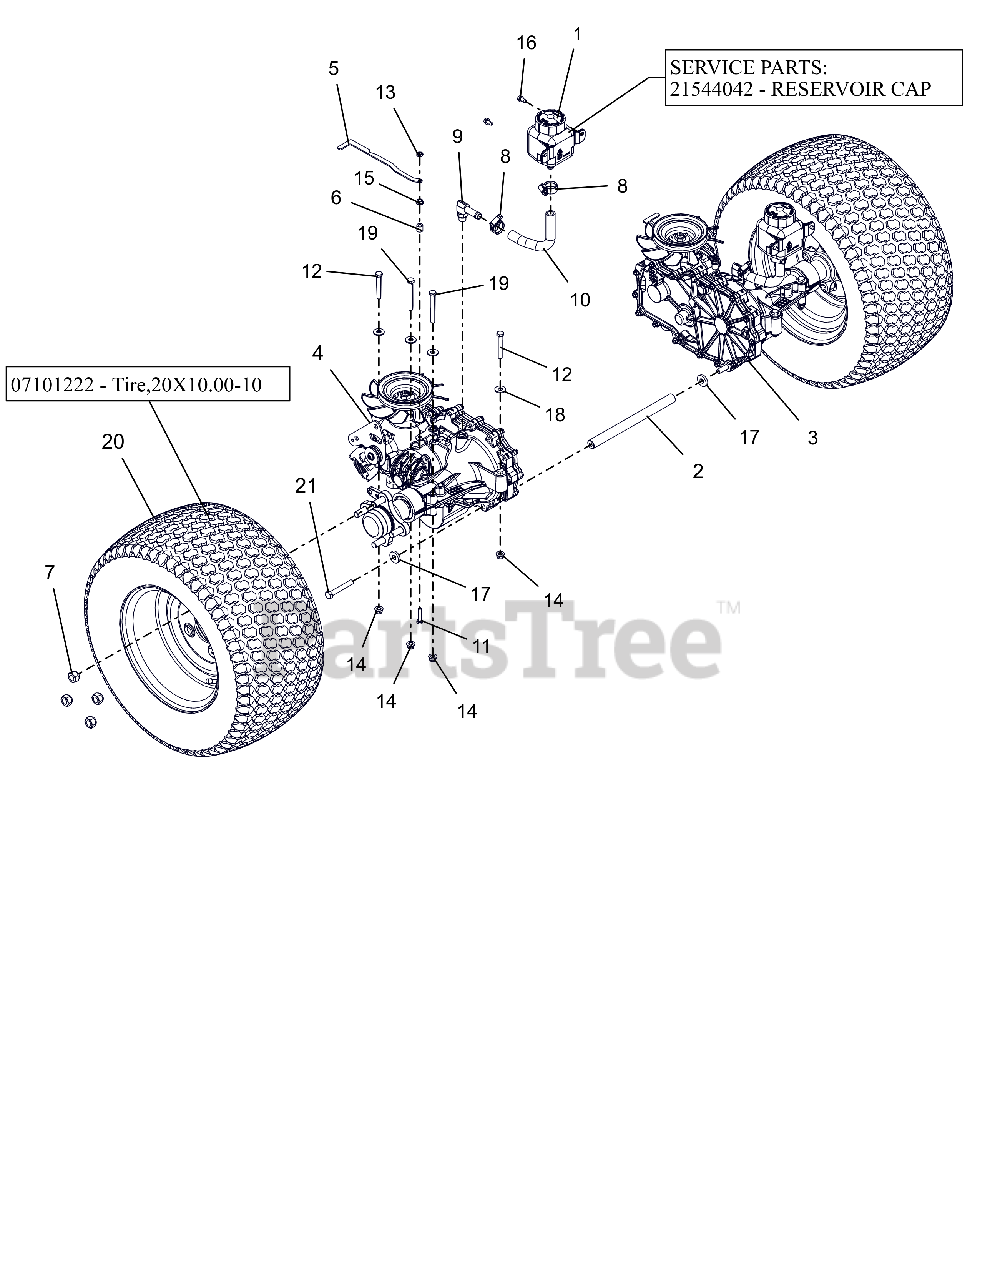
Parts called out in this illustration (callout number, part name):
1	TANK, EXPANSION
1	CAP, HYDRO RESERVOIR REPLAC.
2	ROD, TRANSAXLE BRACE (LONG)
3	TRANSAXLE,ZT2800 LH
4	TRANSAXLE,ZT2800 RH
5	BRKT, DUMP VALVE
6	BSHG-SLV .265X.500X.500
7	WHEEL NUT .500-20 YZ
8	CLAMP,.88 DIA. HOSE
9	FITTING, HYD (90 DEG)
10	HOSE, FORMED LH XL
11	@BLT-HEX .25-20X1.25 GR5 YWZC
12	@BLT-HEX .31-18X2.25 GR5 YWZC
13	NUT-LK-CTR JAM .25-20 YWZC
14	@NUT-LK-NYL-FLG .31-18 YWZC
15	@NUT-SPNLK-FLG .25-20 YWZC
16	SCR-TAP .25-20X.50 HWH TR YWZ
17	WSHR-FL-STL .406X1.00X.188 YWZ
18	@WSHR-FL-STL.38X.875X.083 YWZC
19	@BLT-HEX .31-18X2.75 GR5 YWZC
20	ASM, WHL/TIRE 20X10.00-10
20	TIRE, 20X10.00-10 (OTR)
21	@BLT-HEX .38-16X2.50 GR5 YWZC
